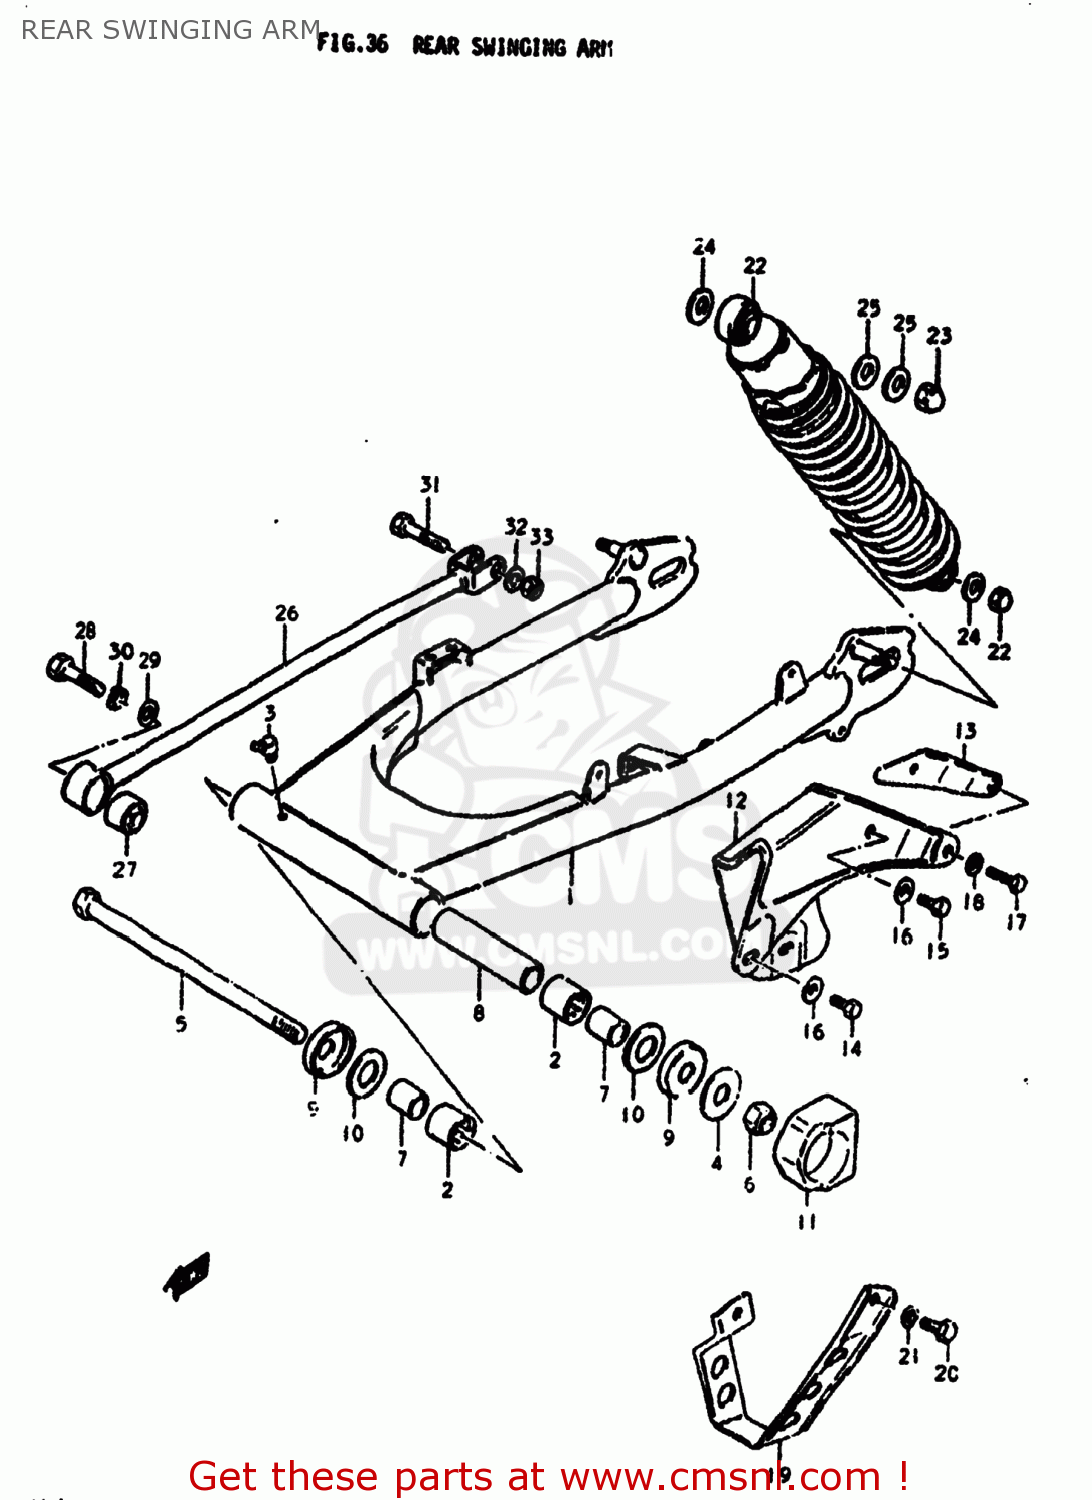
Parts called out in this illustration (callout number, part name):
1	SWING ARM ASSEMBLY,REAR
2	BEARING(22X29X20)
3	NIPPLE,GREASE
4	SHIM
5	SHAFT,REAR SWING ARM
6	NUT 14MM
7	SPACER,RR SWGARM PIVOT
8	SPACER
9	COVER,RR SWGARM DUST SEAL
10	WASHER
11	BUFFER,CHAIN TOUCH DEFENSE
12	CASE,CHAIN
13	REINFORCEMENT,CHAIN CASE
14	BOLT
15	BOLT(6X8)
16	WASHER
17	BOLT, UPPER
18	WASHER
19	GUIDE,CHAIN
20	BOLT 8X12
21	LOCK WASHER
22	ABSORBER ASSEMBLY,REAR SHOCK
23	NUT, LOWER LH
24	WASHER
25	WASHER
26	TORQUE LINK,REAR
27	BUSH
28	BOLT 10X40
29	WASHER
30	LOCK WASHER
31	BOLT 10X40
32	WASHER
33	NUT
